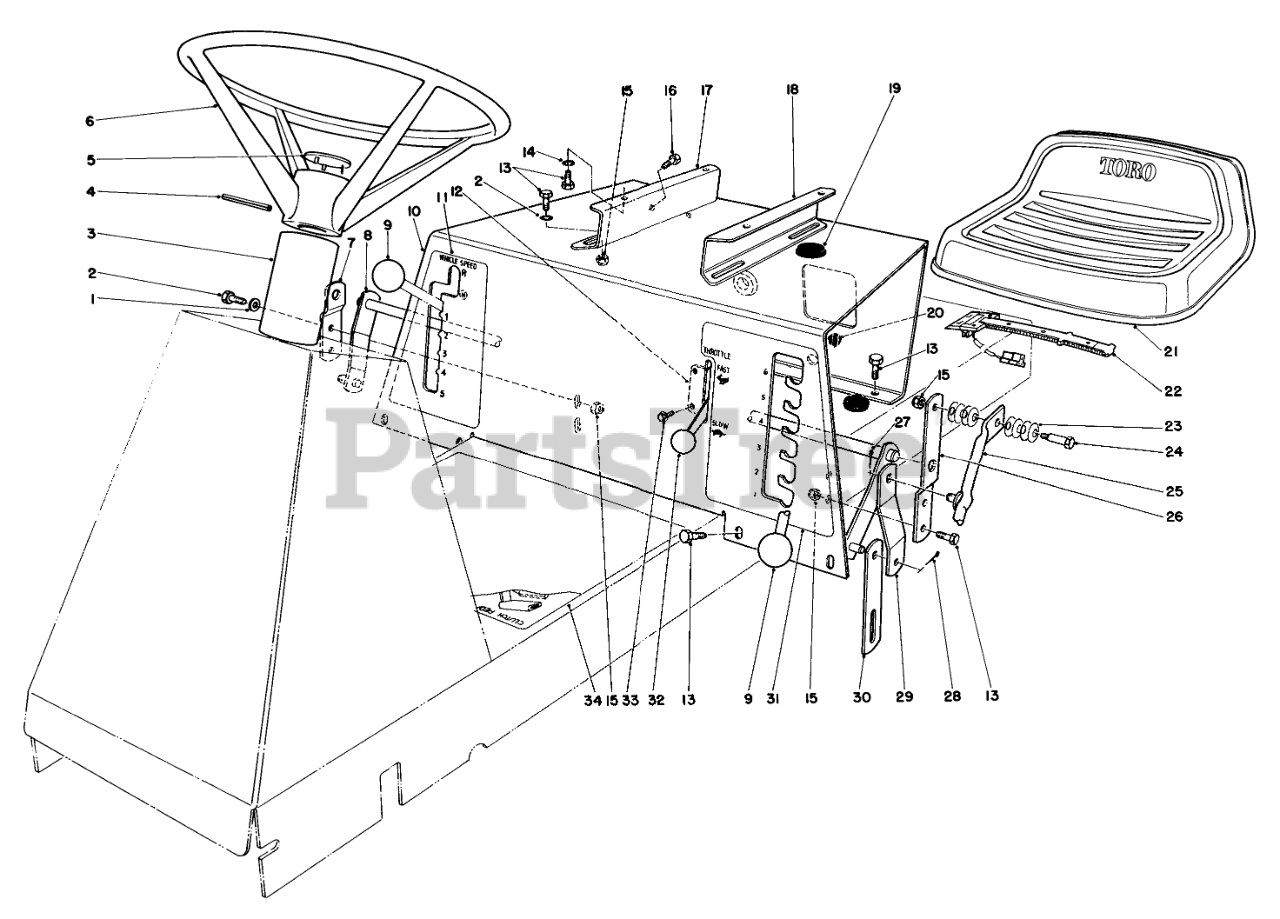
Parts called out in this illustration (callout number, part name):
1	WASHER-PLAIN
2	SCREW-HH
3	STRG. SHAFT COVER
4	PIN-ROLL
5	Cap-Steering Wheel
6	Steering Wheel
7	Bracket H.O.C Support
8	HOC LEVER WA B
10	Support Seat
11	Decal-Transmission
12	Throttle Control
13	SCREW-HH
14	WASHER-LOCK
15	NUT-LOCK, CONE
16	SCREW-HH
17	Bracket-Seat LH.
18	Bracket-Seat RH.
19	GROMMET
20	GROMMET
21	Seat
22	SWITCH-SEAT
23	WASHER-BELLEVILLE
24	BOLT-SHOULDER
25	HOC LEVER WA B
26	Bracket
27	PIN-COTTER
28	PIN-COTTER
29	Bracket-Height Of Cut Engagement
30	Link-Deck Suspension
31	H.O.C. DECAL
32	KNOB-CONTROL
33	SCREW-HWHTF
34	Decal-Instructions
